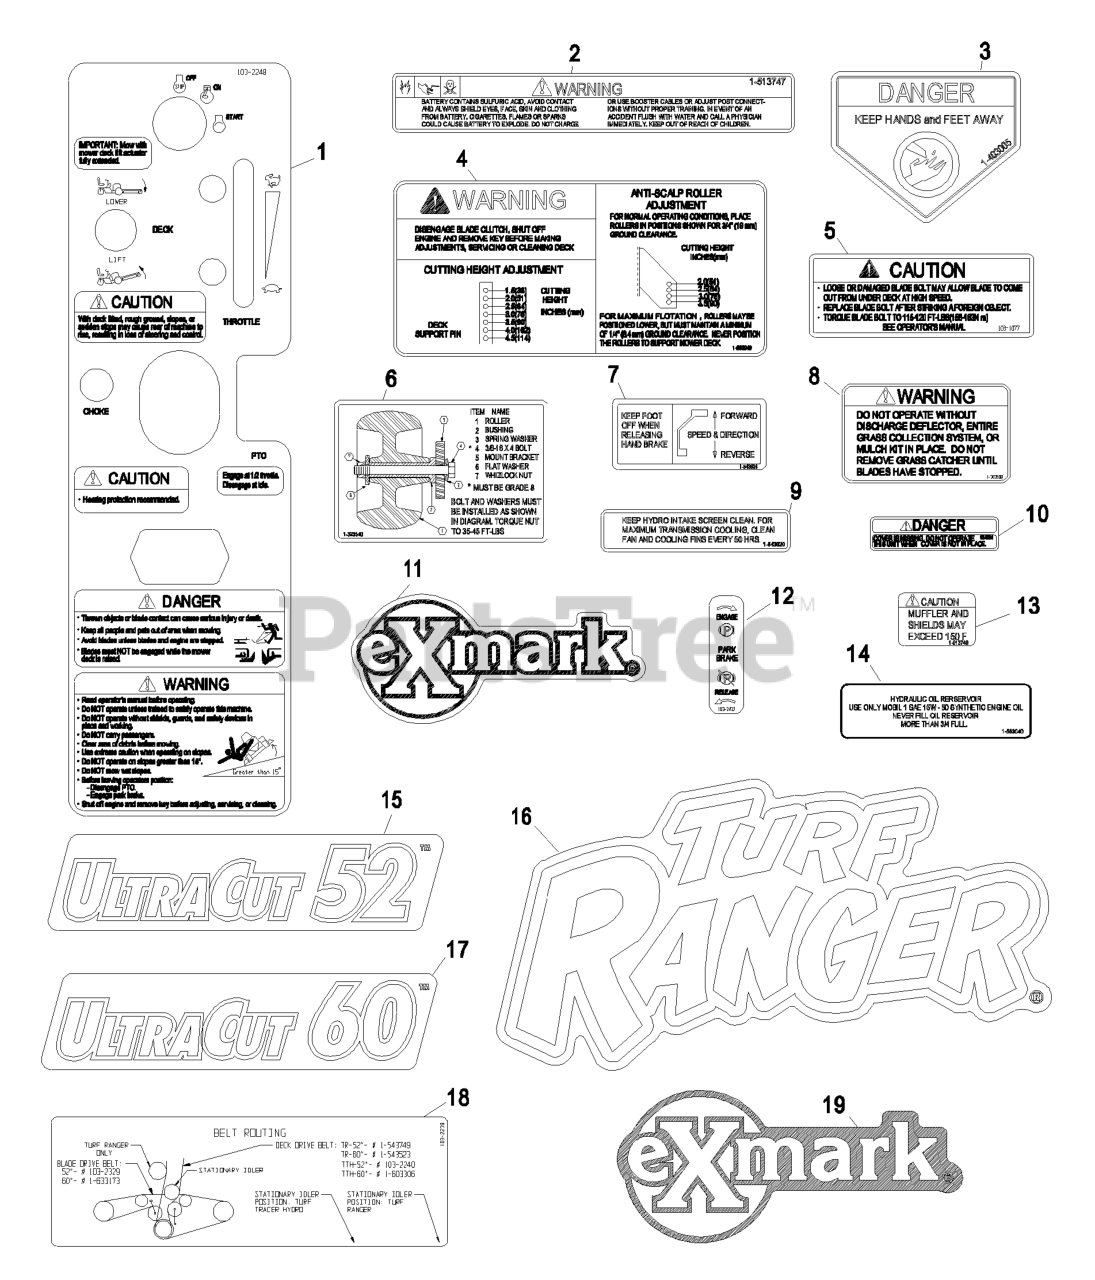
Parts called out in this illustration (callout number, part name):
1	DECAL, CONSOLE
2	DECAL-BATTERY
3	DECAL-DANGER
4	DECAL,ANTI SCALP
5	DECAL,BOLT TORQUE
6	DECAL,ROLLER MOUNTING
7	DECAL,FOOT PEDAL
8	DECAL-WARNING, DISCHARGE
9	DECAL,INTAKE
10	DECAL-COVER, MISSING
11	DECAL,EXMARK LOGO
12	DECAL,PARKING BRAKE
14	DECAL,HYDRAULIC TANK
15	DECAL,ULTRACUT 52
17	DECAL,ULTRACUT 60
18	DECAL,BELT ROUTING
19	DECAL,EXMARK LOGO
